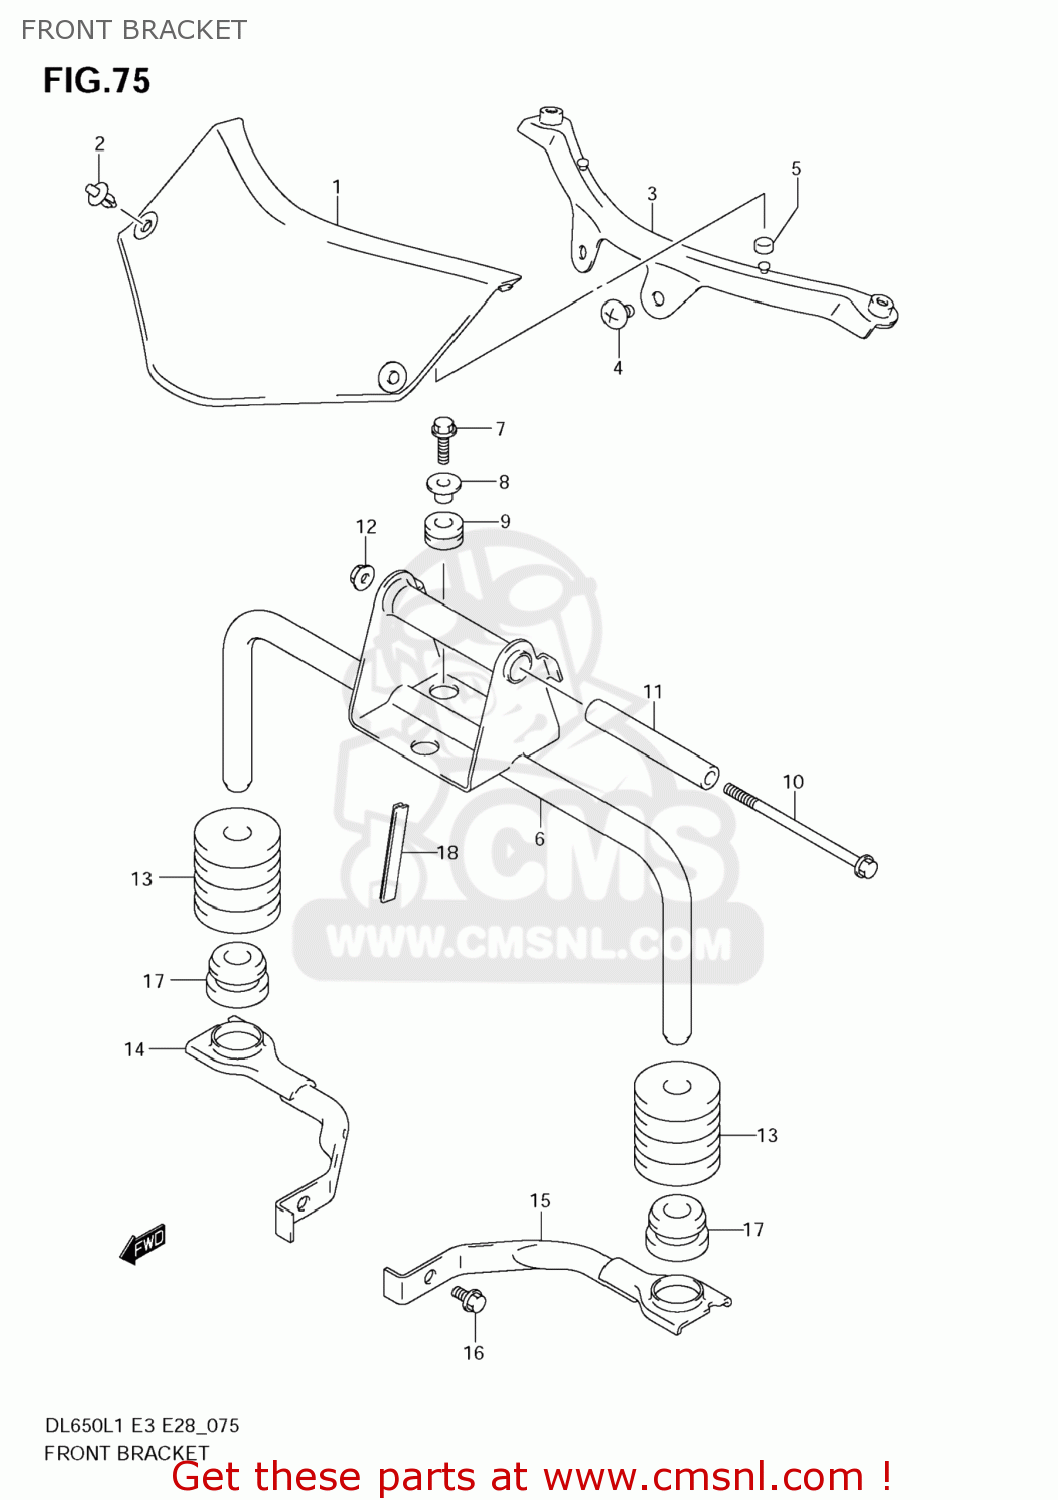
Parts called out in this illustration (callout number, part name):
1	COVER,FUEL TANK FR
2	CLIP(BLACK)
3	BRACKET,FR COVER
4	SCREW
5	CUSHION,FUEL TANK FR COVER
6	BRACKET,FUEL TANK FR
7	BOLT
8	WASHER
9	CUSHION
10	BOLT
11	SPACER,FUEL TANK RR
12	NUT
13	CUSHION,FUEL TANK FR
14	BRACKET,FR SIDE,R
15	BRACKET,FR SIDE,L
16	BOLT
17	CUSHION
18	MOLDING
